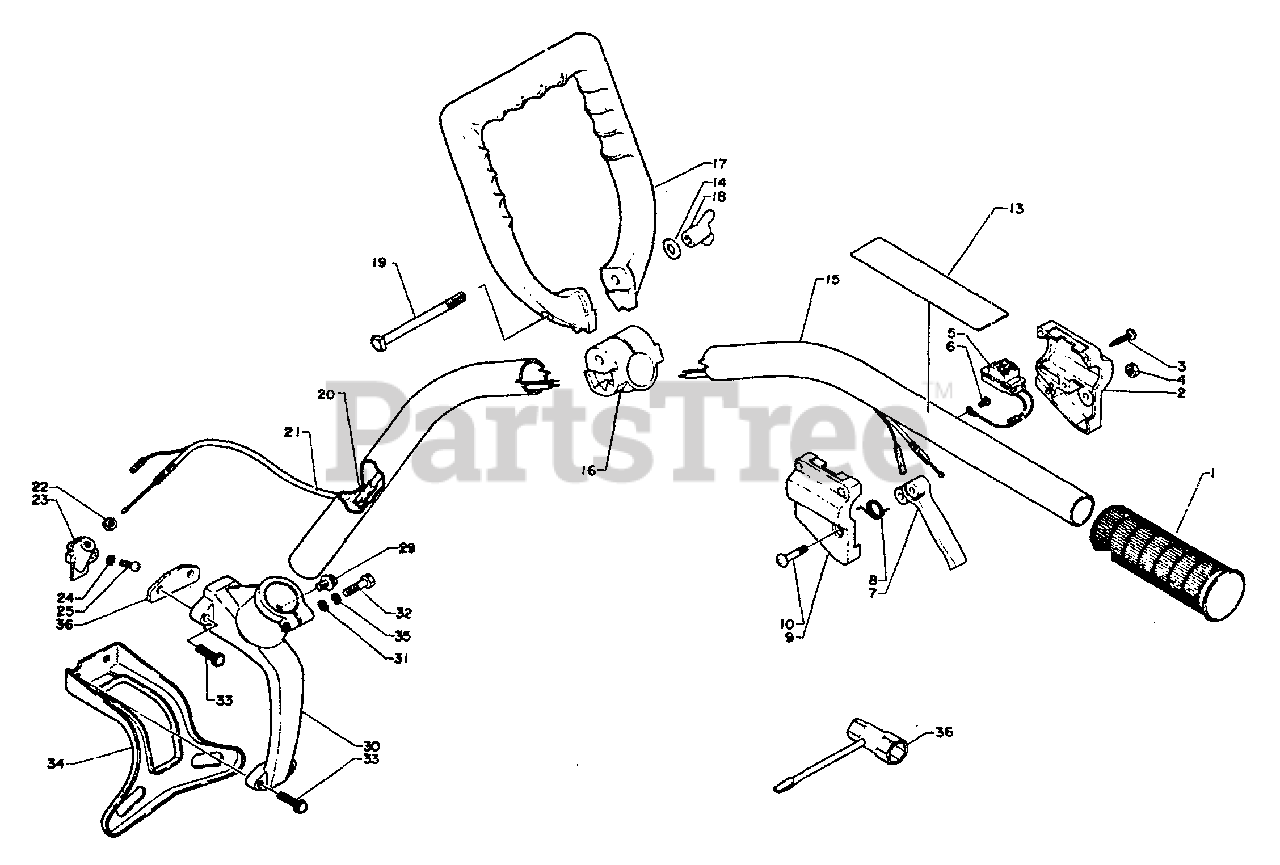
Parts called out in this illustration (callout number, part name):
1	GRIP
2	BRACKET, TRIGGER
3	SCREW 4×25
4	LOCKNUT - 5
5	IGNITION SWITCH ASSY
6	SCREW - 4×8
7	TRIGGER, THROTTLE
8	SPRING, THROTTLE
9	BRACKET, THROTTLE CONTROL - LEFT
13	LABEL
15	PIPE, MAIN
16	BRACKET, HANDLE
17	HANDLE
18	NUT - 6 -- BUTTERFLY
19	BOLT
20	COVER, THROTTLE CABLE
21	CABLE, THROTTLE
23	HOLDER, CABLE
24	WASHER - 4
25	SCREW 4×12
29	SCREW 5×10
30	BRACKET
31	WASHER, FLAT 5.5×10×0.8
32	BOLT - 5×25
33	SCREW 5×20
34	STAND
35	WASHER, SPRING 5
36	WRENCH
